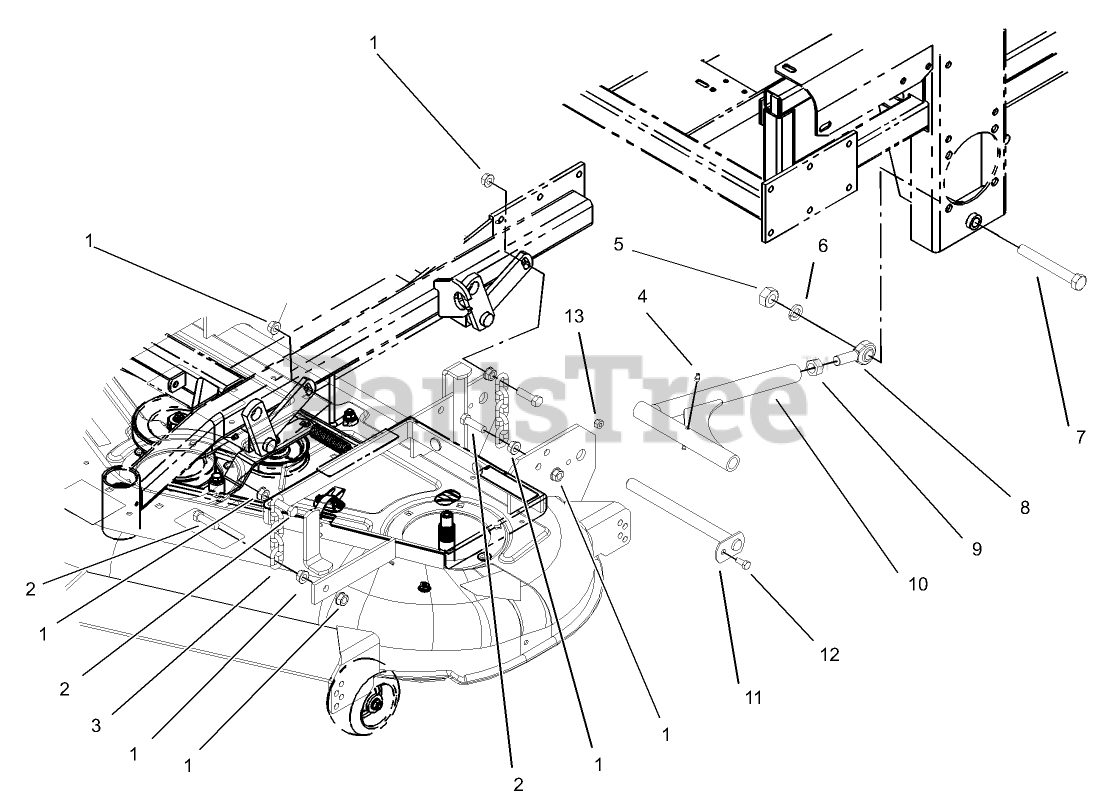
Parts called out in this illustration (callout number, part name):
1	NUT-HF
2	SCREW-CAP, HH
3	CHAIN-LIFT, DECK
4	FITTING-GREASE
5	NUT-HEX
6	WASHER-LOCK
7	SCREW-HH
8	BALLJOINT-SPHERICAL
9	NUT-HEX
10	STRUT
11	PIN-STRUT
12	SCREW-HH
13	NUT-LOCK, NI
